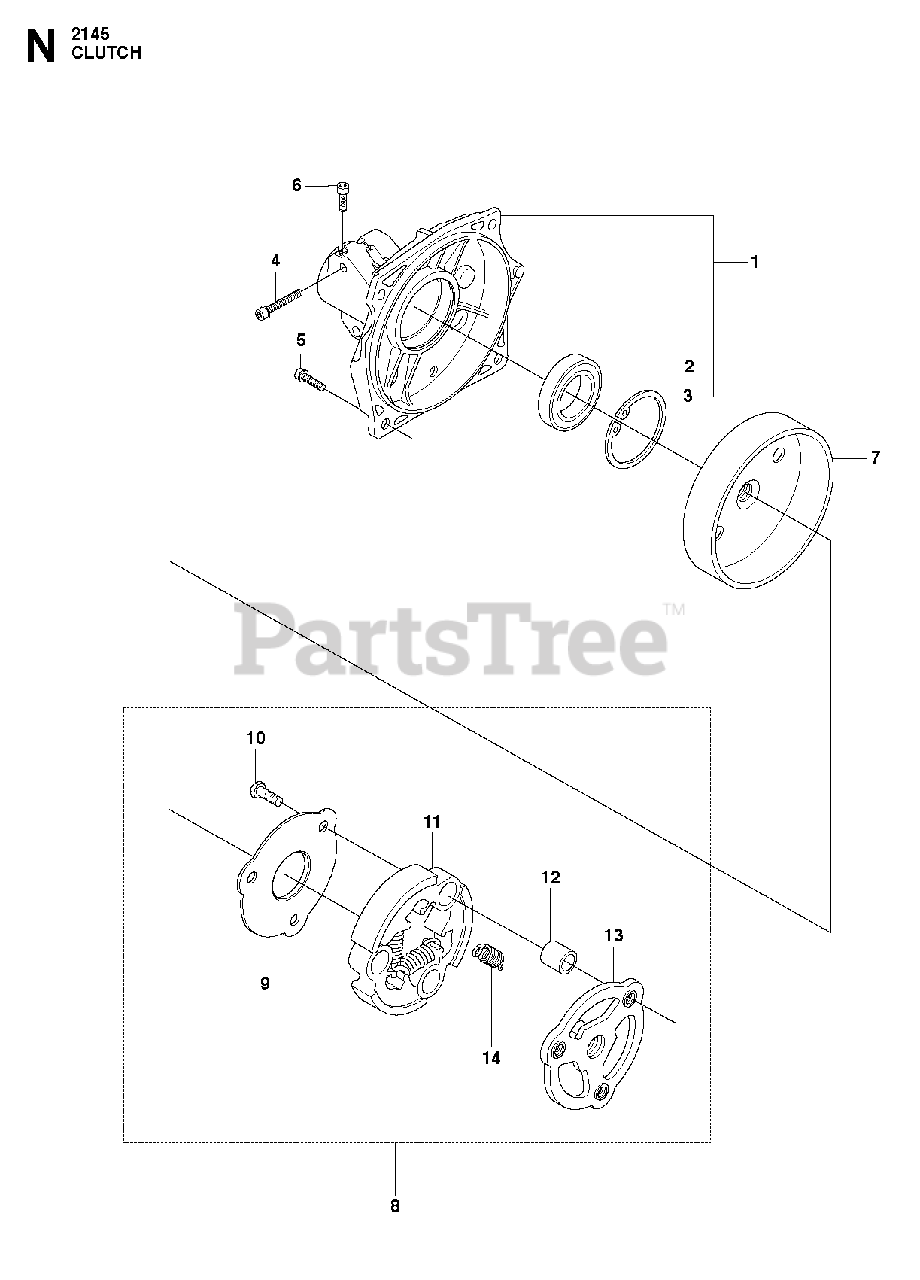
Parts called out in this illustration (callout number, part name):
1	CLUTCH COVER
2	BALL BEARING 6202-2RS1
3	RETAINING RING SGH 35
6	SCREW MC6LS 5X12
7	CLUTCH DRUM ASSM.
8	CLUTCH CPL
9	WASHER
10	SCREW
11	CLUTCH
12	BUSHING
13	HUB
14	CLUTCH SPRING
